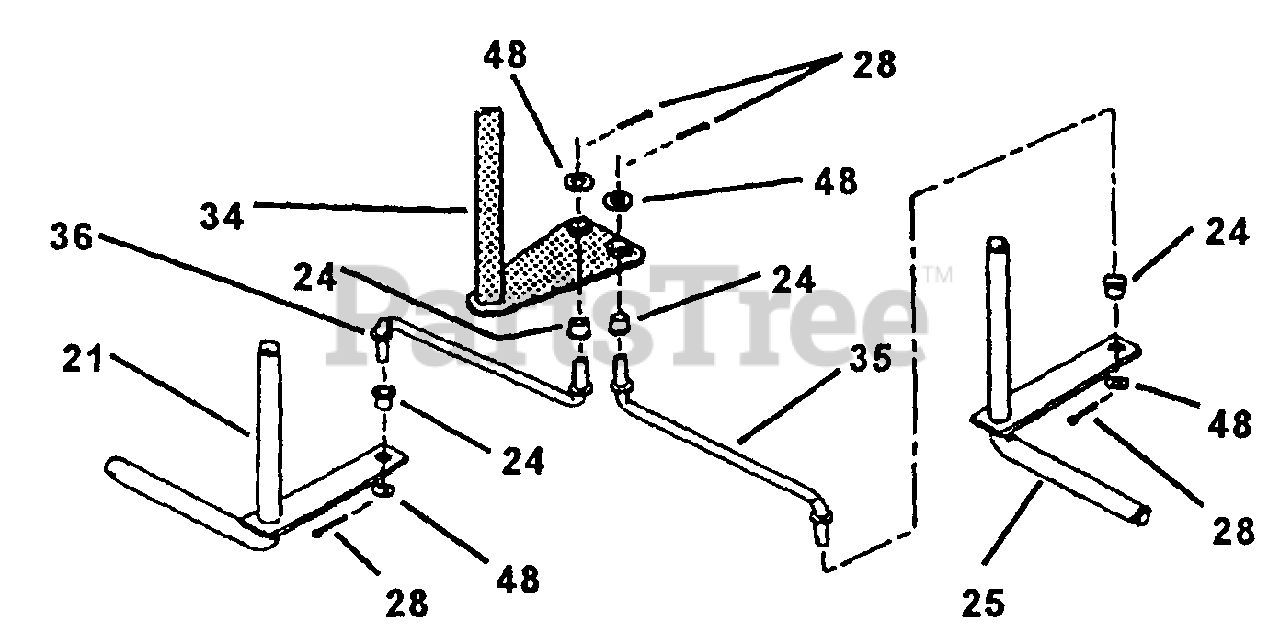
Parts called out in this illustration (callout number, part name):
21	PIN, Narrow King (Right Side)
24	BUSHING, Tie Rod
25	PIN, Narrow King (Left Side)
28	COTTER-PIN, 5/32 x 1"
34	SHAFT, Steering (Narrow Front End)
35	TIE-ROD, Left Side 7.67"
36	TIE-ROD, Right Side 7.67"
48	WASHER, 3/8" Flat
